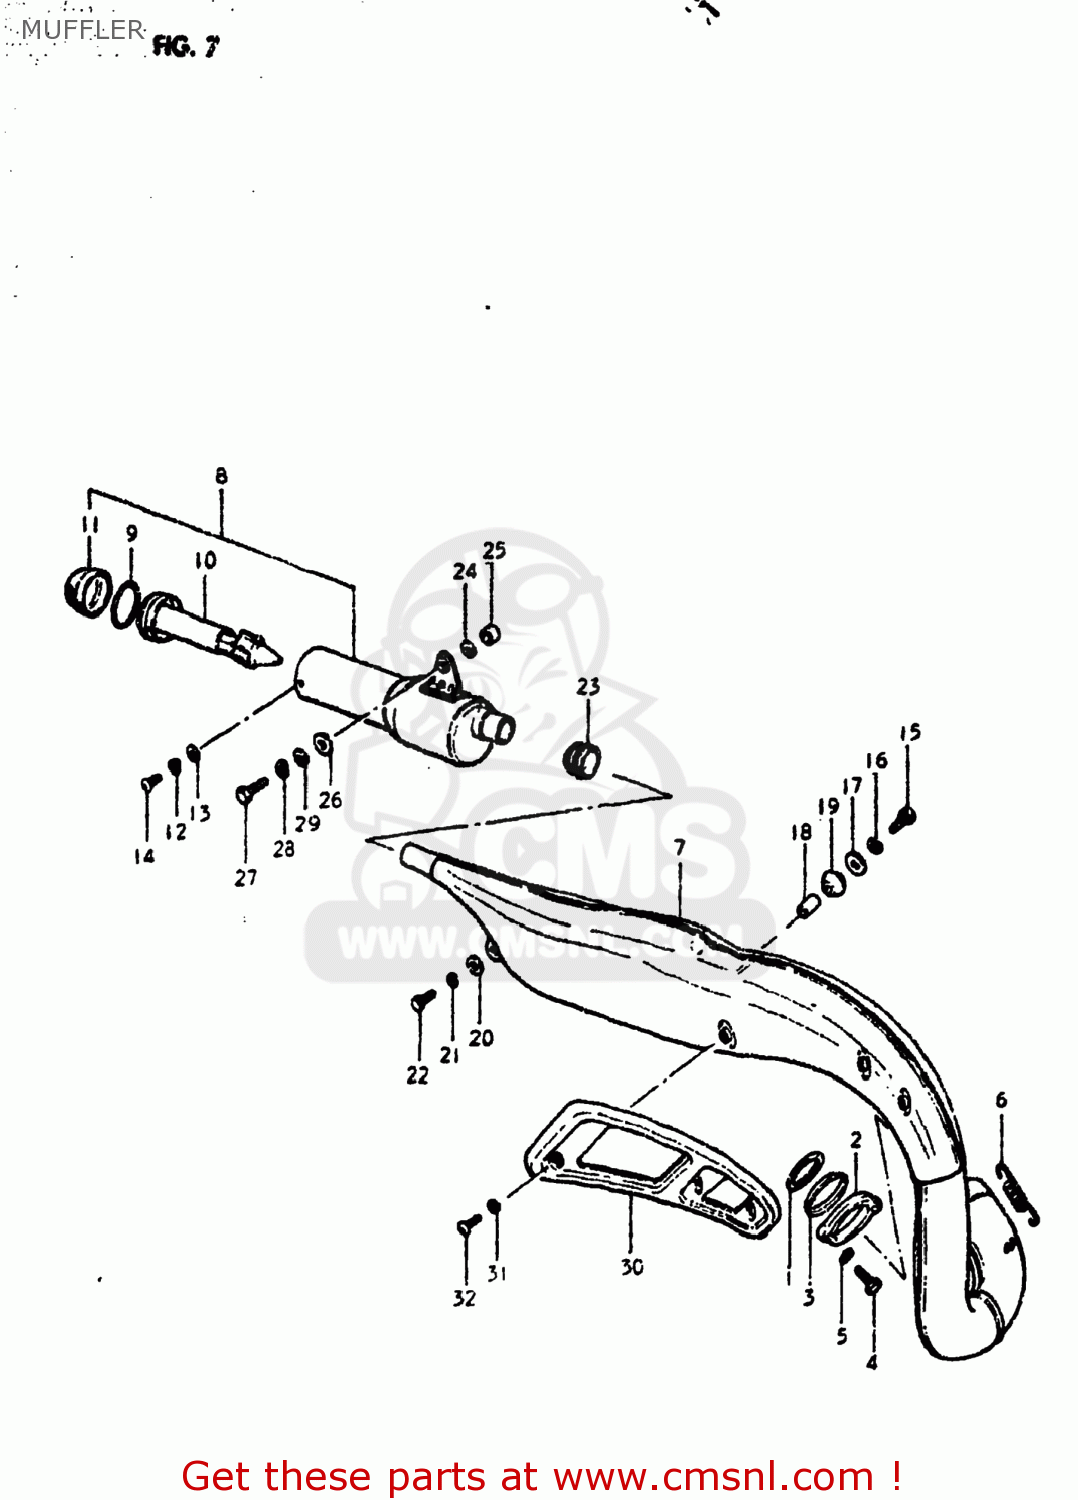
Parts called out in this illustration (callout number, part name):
1	GASKET,EXHAUST PIPE (NAS)
2	CLAMP,EXHAUST PIPE
3	GASKET,EXHAUST PIPE
4	BOLT
5	LOCK WASHER
6	SPRING
7	BODY,MUFFLER
8	MUFFLER ASSEMBLY
9	O-RING (D:3.5 ID:54.4)
10	TUBE,MUFFLER CLEAN OUT
11	COVER,SECOND MUFFLER TAIL
12	LOCK WASHER
13	WASHER
14	SCREW(6X8)
15	BOLT (8X30)
16	LOCK WASHER
17	WASHER (8.7X22X2)
18	SPACER (8X12X15)
19	DAMPER,MUFFLER,FR
20	WASHER
21	LOCK WASHER
22	BOLT
23	CONNECTOR,MUFFLER
24	WASHER
25	SPACER
26	CUSHION
27	BOLT
28	LOCK WASHER
29	WASHER
30	COVER,MUFFLER
31	LOCK WASHER
32	SCREW
